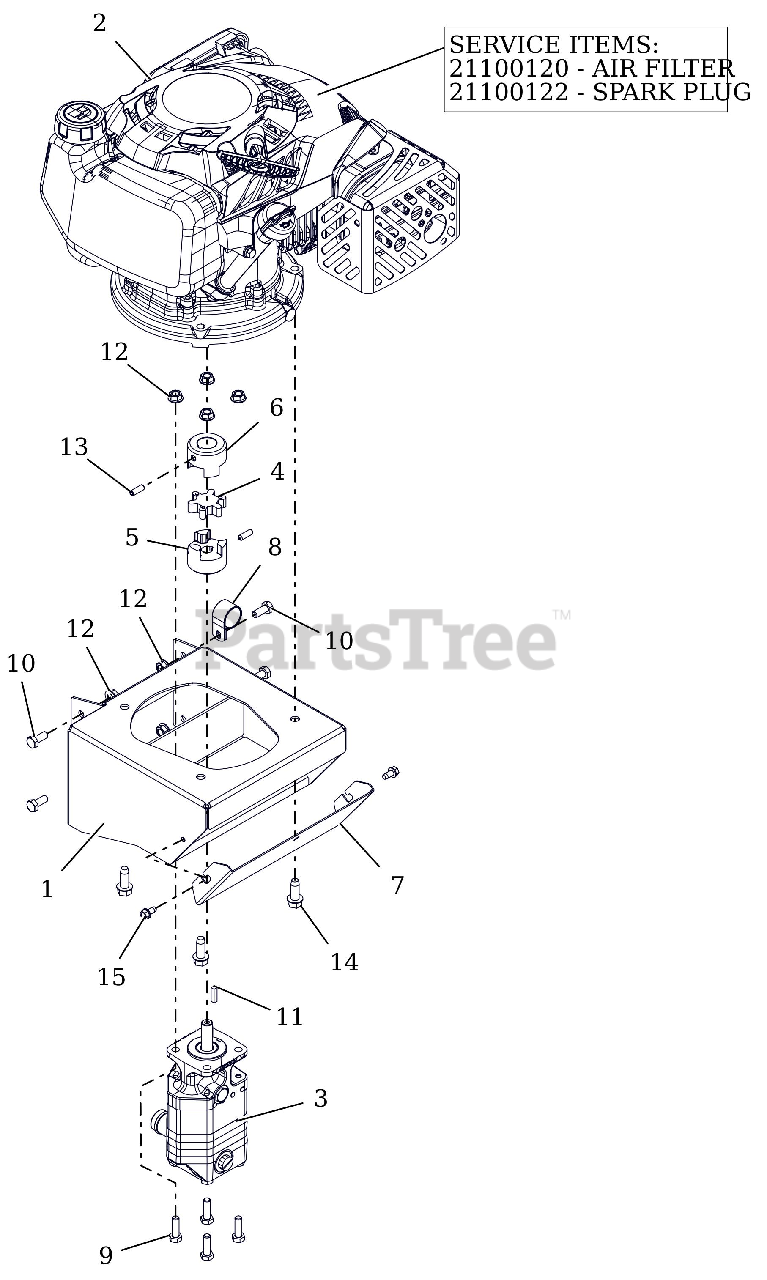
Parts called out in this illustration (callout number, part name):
1	ENGINE MOUNT W/SAFTY DECAL-22T
2	ENGINE, SUBARU EA175V
2	FILTER, AIR- SUBARU PAPER
2	PLUG, SPARK
3	PUMP,SPLITTER-11 GPM
4	SPIDER - URETHANE
5	COUPLER - DRIVE 1/2"
6	COUPLER - DRIVE, 7/8"
7	COVER, COUPLING
8	CLAMP, COUSHIONED STEEL REV
9	@BLT-HEX .31-18X1.00 GR5 YWZC
10	@BLT-HEX .31-18X.75 GR5 YWZC
11	KEY-SQ .188X.75X.188
12	@NUT-LK-TOP-FLG .31-18 YWZC
13	SCR,SET .25-20X.75 PCPT SH
14	@SCR-TAP .38-16X1.00 HWH TR YZ
15	SCR-TAP .25-20X.50 HWH TR YWZ
